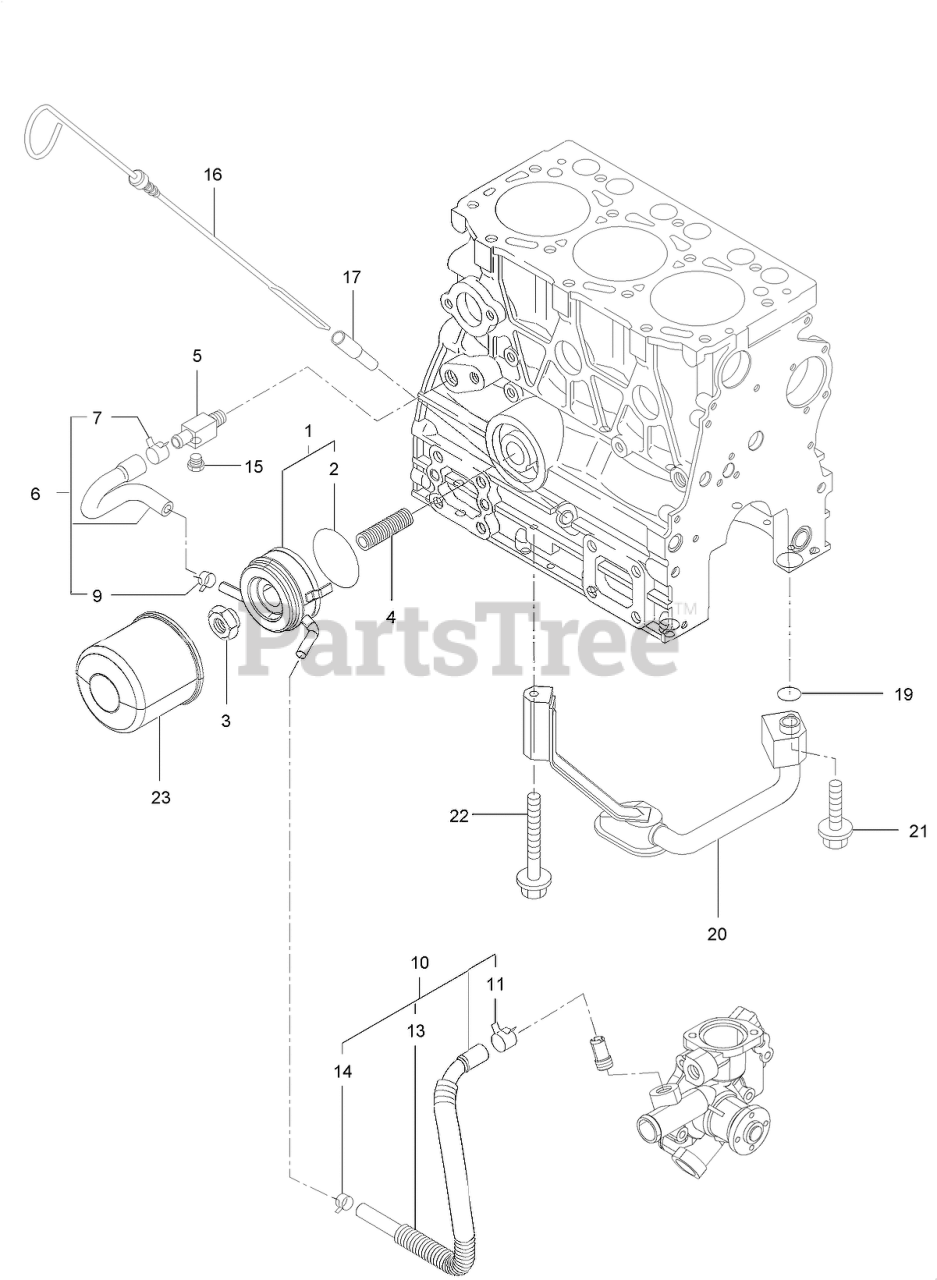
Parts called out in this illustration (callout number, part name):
1	COOLER-OIL
3	NUT-COOLER, OIL
4	STUD-LO FILTER
6	PIPE ASM-COOLER IN
9	CLAMP-HOSE
10	PIPE ASM
14	CLAMP-HOSE
15	PLUG-DRAIN
16	DIPSTICK
17	GUIDE-DIPSTICK
20	PIPE ASM-OIL INLET
23	FILTER ENGINE OIL
